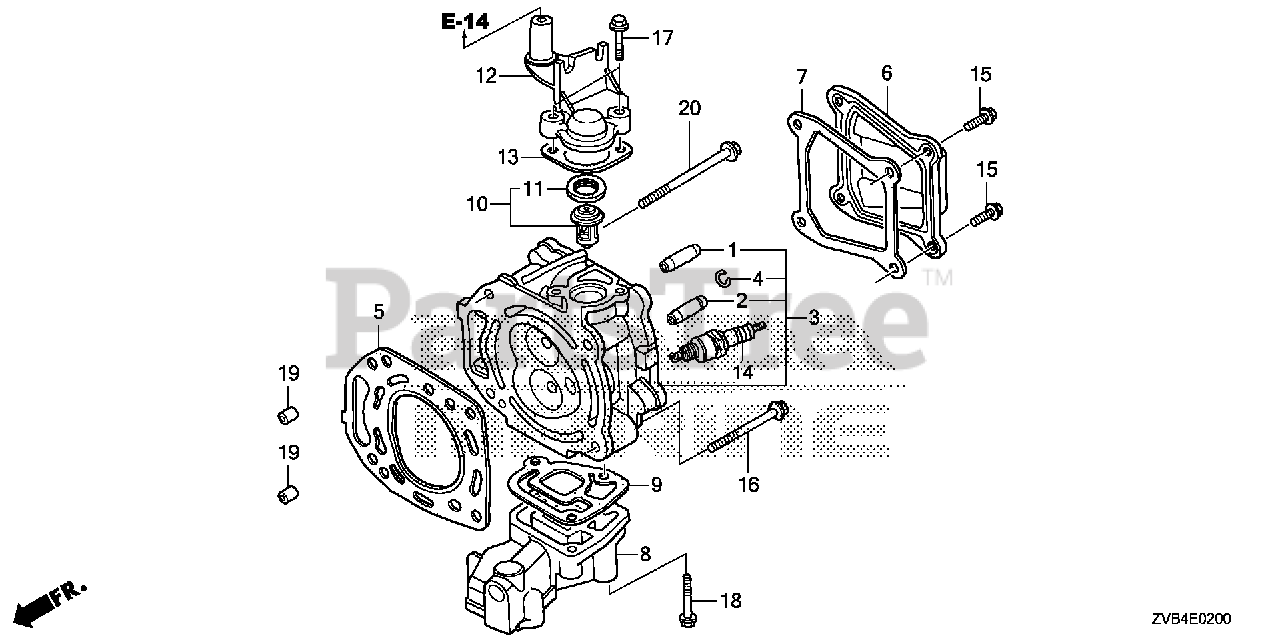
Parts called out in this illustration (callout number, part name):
1	GUIDE, VALVE (OVER SIZE) Use from Engine SN 6324986.
2	GUIDE, EX. VALVE (OVER SIZE)
3	CYLINDER HEAD *NH8* (DARK GRAY)
4	CLIP, VALVE GUIDE Use from Engine SN 1231803.
5	GASKET, CYLINDER HEAD
6	COVER, HEAD
7	GASKET, HEAD COVER
8	MANIFOLD, EX. *NH8* (DARK GRAY)
9	GASKET, EX. MANIFOLD
10	THERMOSTAT ASSY.
11	RUBBER, THERMOSTAT
12	COVER, THERMOSTAT *NH8* (DARK GRAY)
13	GASKET, THERMOSTAT COVER
14	SPARK PLUG (BKR6E-E)
15	BOLT, FLANGE (6X12)
16	BOLT, FLANGE (8X60)
17	BOLT, FLANGE (6X22)
18	BOLT, FLANGE (6X32)
19	PIN A, DOWEL (10X16)
20	BOLT, FLANGE (8X90)
